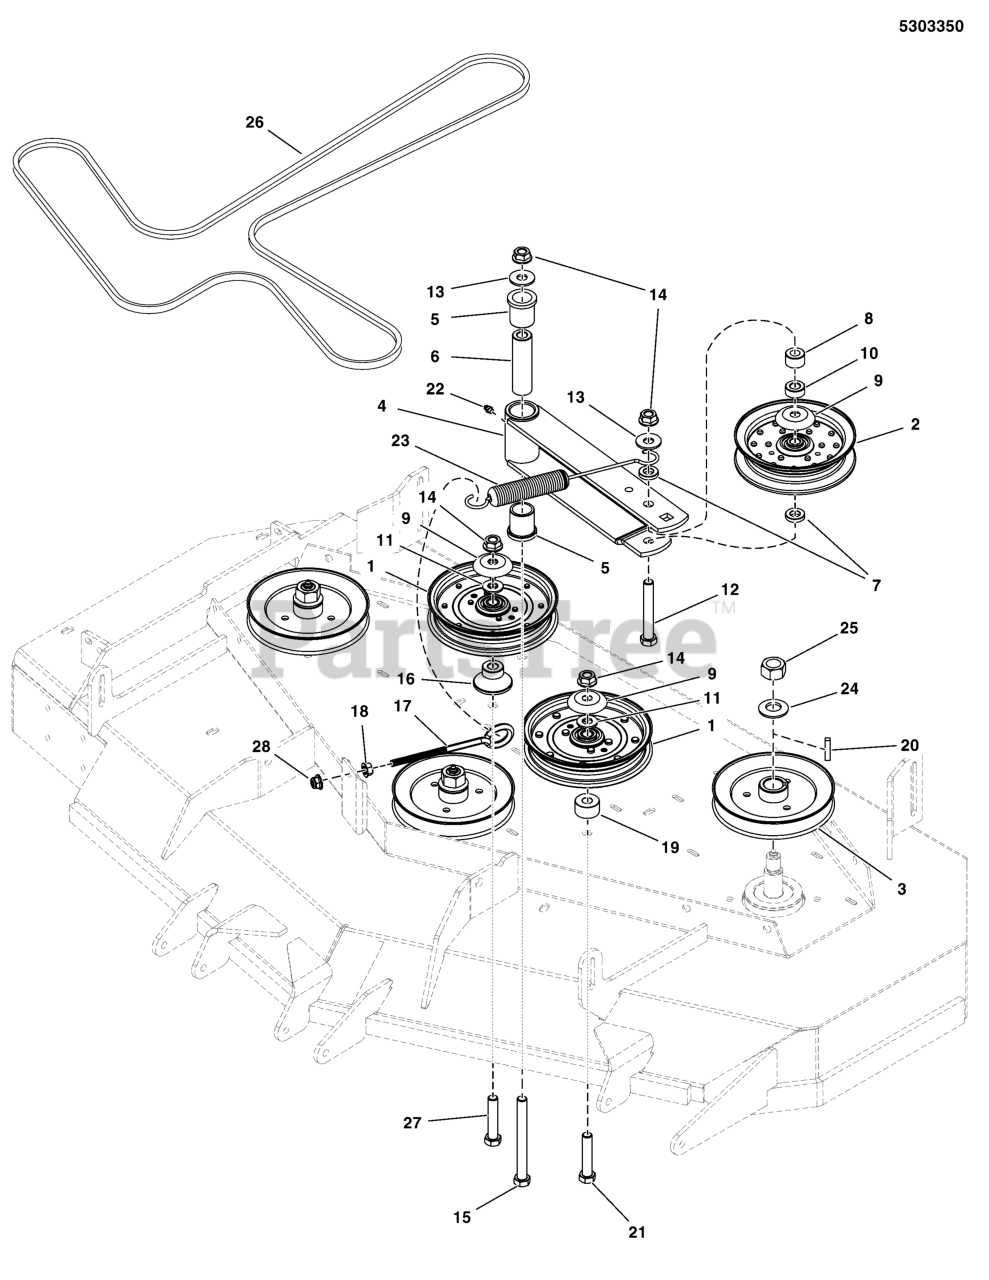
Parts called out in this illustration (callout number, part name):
3	PULLEY, 5.926 OVER BALL
4	WELD, IDLER ARM - BLK
5	BUSHING, FLANGE
6	SPACER, .52 X 1.00 X 3.50
7	SPACER, .52 X 1.00 X .22, PM, CZ
8	SPACER, .52 X 1.00 X .63, CZ
9	SHIELD, PULLEY BEARING, CZ
10	SPACER, .52 X 1.00 X .44, CZ
11	WASHER, 1/2 SAE
12	BOLT, 1/2-13 X 3-1/2, HEX HD, GD5, CZ (SV)
13	WASHER, 1/2 USS
14	NUT, Hex Flange, Nylock, 1/2-13
15	BOLT-1/2-13 X 5 GD5 YZ
16	IDLER MOUNT
17	EYE BOLT, 3/8-16 X 6.88, 3THRD, 1EYE
18	NUT, 3/8-16 HEX SERRATED FLANGE
19	SPACER, .52 X 1.25 X .70, CZ
20	KEY, 1/4 SQ X 1-1/4
21	BOLT, 1/2-13 X 2-1/2" GD5 CZ
22	GREASE FITTING, 1/4-28 STRAIGHT
23	SPRING-EXT, 1.04 ODX10.535LGX.148WR, BLK
24	WASHER, 3/4 BELLEVILLE
25	NUT, 3/4-16 HEX
26	BELT, 5V, 163.40EL, LG ARAMID, WRPD, RC
27	BOLT, 1/2-13 X 3" GD5 CZ
28	NUT, 3/8-16 HEX NYLOCK FLANGE
